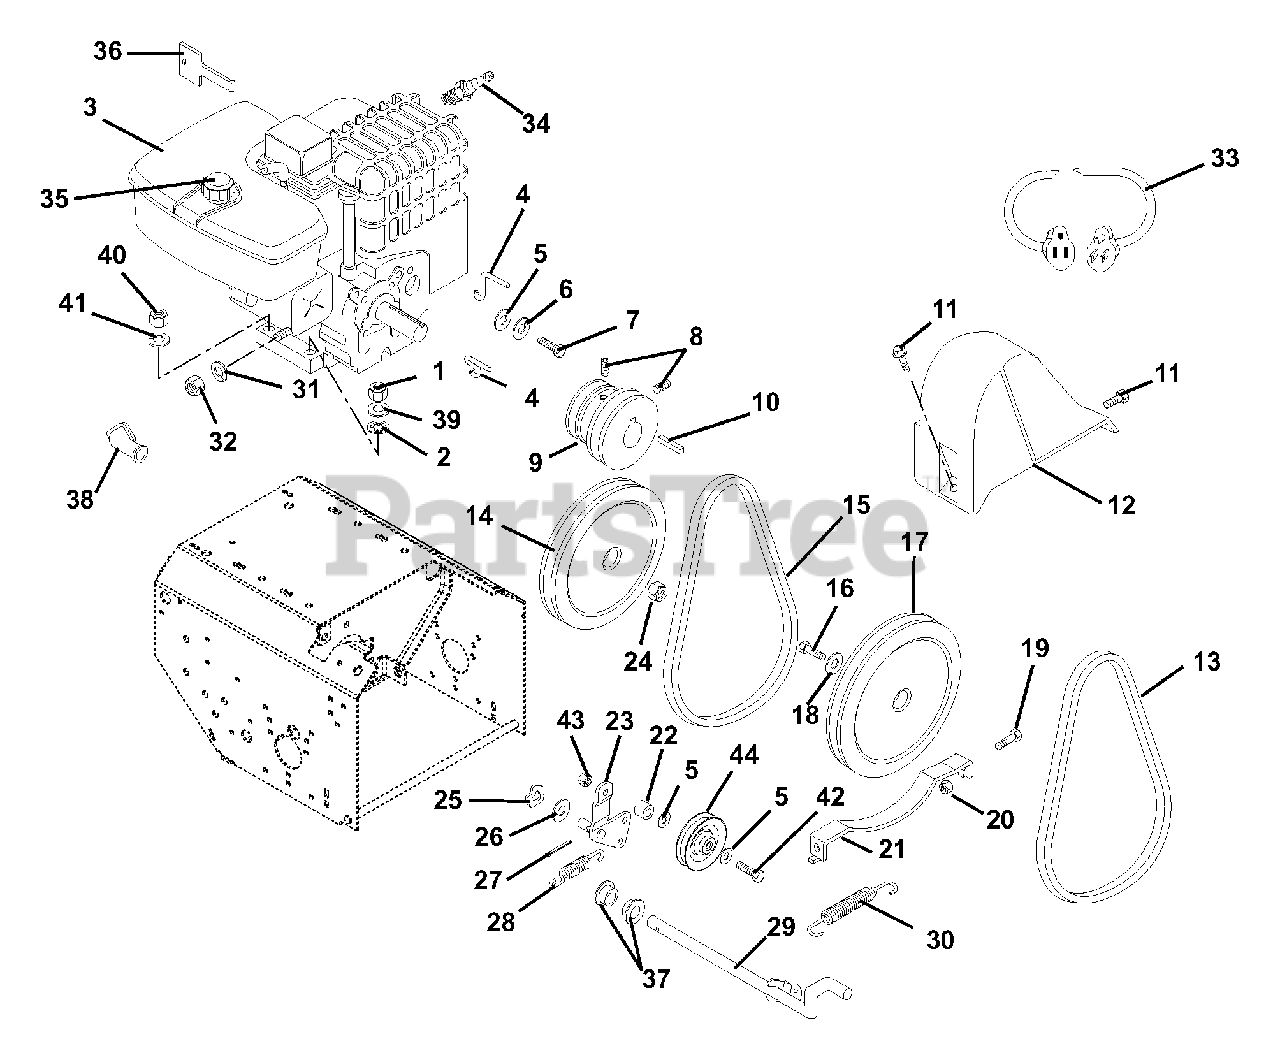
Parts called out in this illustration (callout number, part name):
1	@NUT-LK-CTR .31-18 YWZC
2	WSHR-LOCK INT .31 YWZC
3	ENGINE, 11.5HP OHV TEC.- 120V
4	BELT FINGER
5	@WSHR-FL-STL.38X.875X.083 YWZC
6	@WSHR-LK .31X.078 REG YWZC
7	BLT-HEX .31-24X.75 YWZC GR5
8	SCR-SET .31-18X.38 SKHCUPDL
9	SHEAVE, ENGINE
10	KEY-STR .25X1.75X.25
11	@SCR-TAP .25-20X.50 HWH TR YWZ
12	COVER, BELT
13	V-BELT, 4L-RAW EDGE
14	PLY-V 8.40X1.00 W/KEY
15	V-BELT, 3L-RAW EDGE
16	BLT-HEX .31-24X.75 YWZC GR5
17	PULLEY, 4L W/HUB, .87 X 8.5
18	WSHR-LK .312X.097 HVY YWZC
19	@BLT-HEX .25-20X.50 GR5 YWZC
20	@NUT-LK-CTR .25-20 YWZC
21	BELT RETAINER
22	SPACER .50 X .32 X .42
23	IDLER ARM
24	@NUT-LK-NYL .625-18 YWZC
25	WAVE WASHER .406X.750X.063FH
26	WSHR-FL-STL .382X.812X.023YWZC
27	@PIN-CTR .09X1.00 EXTPRSQCT YZ
28	SG-TENS .080X.73X3.06 WLD 20
29	SHAFT, ACTIVATING-WELDMENT
30	SG-TENS .047X.44X3.37 WLD 1.47
31	@WSHR-LK-EXT.262X.502X.026YWZC
32	@NUT-HEX .25-20 YWZC
33	CORD, ELECTRIC START CORD 120V
34	PLUG, SPARK
35	CAP, FUEL - TECUMSEH
36	KEY, PUSH/PULL - TECUMSEH
37	BSHG-FLG .500X.625X.500X.750
38	BOOT, EYELET TERMINAL
39	@WSHR-FL-STL.344X.688X.065YWZC
40	@NUT-HEX .31-18 YWZC
41	WSHR-LK .312X.097 HVY YWZC
42	@BLT-HEX .31-18X1.00 GR5 YWZC
43	@NUT-LK-CTR .31-18 YWZC
44	IDLER
